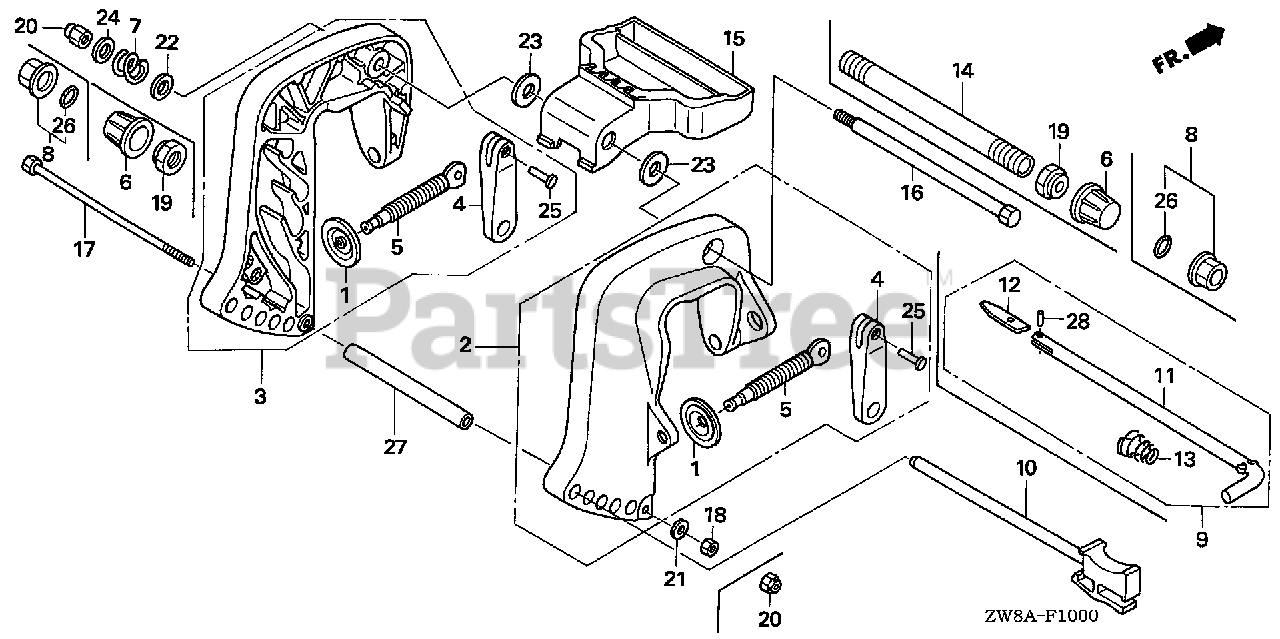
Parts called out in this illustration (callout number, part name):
1	PLATE, PUSH
2	BRACKET, R. STERN *NH282MU* (OYSTER SILVER METALLIC-U)
3	BRACKET, L. STERN *NH282MU* (OYSTER SILVER METALLIC-U)
4	GRIP, CLAMP
5	SCREW, CLAMP
7	SPRING, TILT
10	ROD, ADJUSTING
15	HANDLE, CARRYING
16	BOLT, TILTING
17	BOLT, HEX. (6X160)
18	NUT, HEX. (6MM)
20	NUT, SELF-LOCK (8MM)
21	WASHER, PLAIN (6MM)
22	WASHER, PLAIN (10MM)
23	WASHER (10MM)
24	WASHER (8MM)
25	RIVET (4X22.6)
27	COLLAR, DISTANCE (6MM)
